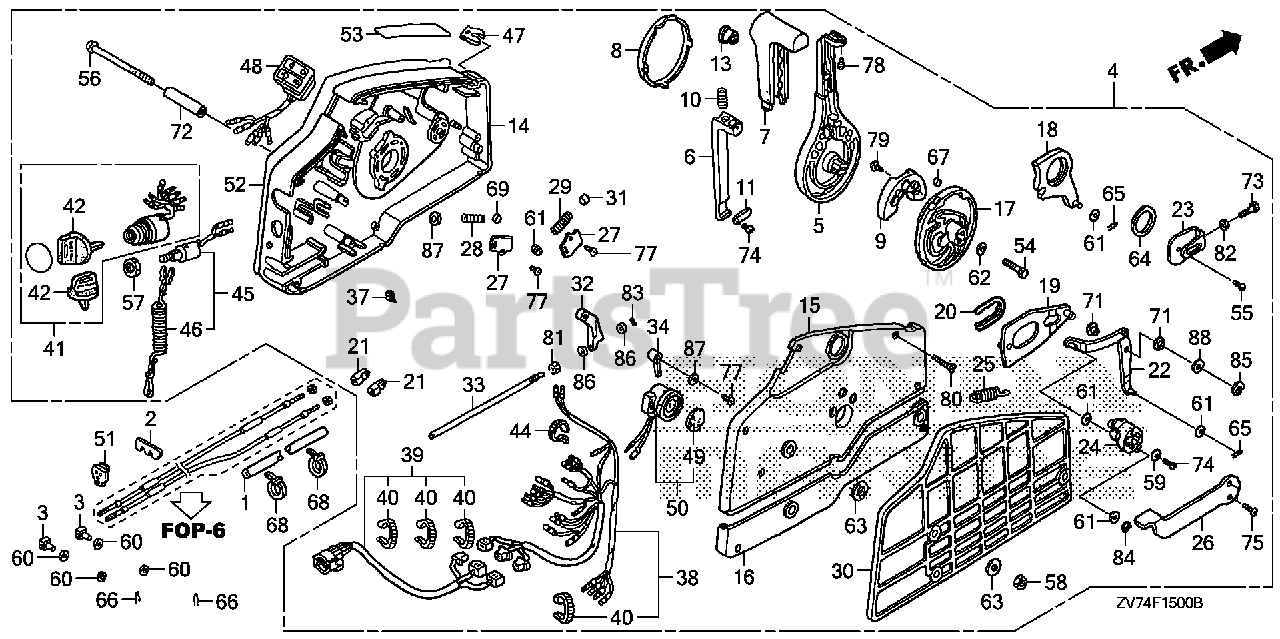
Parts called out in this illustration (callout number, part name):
1	TUBE, CORRUGATE (28MM)
2	PLATE, REMOTE CONTROL CABLE
3	PIVOT, SHIFT
4	S/R SW 2 LIGH MAN TL
4	BOX ASSY., REMOTE CONTROL (A/T)(HI-LEX)
5	HANDLE, REMOTE CONTROL
6	LEVER, HANDLE LOCK
7	GRIP, REMOTE CONTROL HANDLE
8	CAP, HANDLE
9	BLOCK, NEUTRAL LOCK
10	SPRING, REMOTE CONTROL HANDLE
11	PLATE, LEVER SETTING
13	COVER, GRIP
14	HOUSING, REMOTE CONTROL BOX (A)
15	HOUSING, REMOTE CONTROL BOX (B)
16	HOUSING, REMOTE CONTROL BOX (C)
17	WHEEL, CONTROL
18	ARM, SHIFT LINK
19	PLATE, SLIDING
20	COLLAR, SLIDING PLATE
21	PIVOT, SHIFT
22	ARM, LINK JOINT
23	BRACKET, LINK JOINT
24	WHEEL, ACCELERATOR
25	SPRING, ACCELERATOR WHEEL
26	LEVER, IDLE
27	PLATE, SPRING SETTING
28	SPRING, SHIFT CLICK
29	SPRING, CHOKE RETURN
30	SPACER, REMOTE CONTROL BOX
31	SPACER, CLICK SPRING
32	BLOCK, THROTTLE FRICTION
33	BOLT, FRICTION
34	SPACER, NEUTRAL SWITCH
37	SPACER, CABLE CLAMP
38	CABLE ASSY., REMOTE CONTROL (B)
39	CABLE ASSY., SWITCH PANEL
40	TIE, CABLE (2.4X92) (NATURAL)
41	SWITCH ASSY., COMBINATION
42	KEY ASSY., COMBINATION SWITCH (35100-ZV5-003 ONLY)
44	BAND (BLACK 3.5X140)
45	SWITCH ASSY., EMERGENCY STOP
46	WIRE, EMERGENCY
47	CLIP, EMERGENCY LOCK
48	LAMP ASSY., INDICATION (2-LED)
49	PLATE, TURN SIGNAL BUZZER
50	BUZZER, WARNING
51	GROMMET, CASE (LOWER) (A)
52	PLATE, REMOTE CONTROL (CAUTION PICT=SILVER)
52	PLATE, REMOTE CONTROL (COUTION COLOR=RED & YELLOW)
53	MARK, FAST IDLE
54	BOLT, FLANGE (8X35)
55	SCREW, PAN (6X10)
56	SCREW (6X95)
57	NUT, HEX. (16MM)
58	NUT, HEX. (6MM)
59	WASHER, PLAIN (5MM)
60	WASHER, PLAIN (6MM)
61	WASHER, PLAIN (6MM)
63	WASHER (6MM)
64	WASHER (28MM)
65	PIN, LOCK (6MM)
66	PIN, SPECIAL LOCK (6MM)
67	PIN (6X6)
68	BAND, SELF-LOCK
69	ROLLER, CLICK
71	COLLAR, LINK JOINT
72	COLLAR, DISTANCE (6X10X43.5)
73	BOLT, HEX. (5X16)
74	SCREW, PAN (5X10)
75	SCREW, FLAT (5X12)
77	SCREW, TAPPING (5X10)
78	SCREW, TAPPING (5X12)
79	SCREW, TAPPING (6X16)
80	SCREW, TAPPING (5X25)
81	NUT, HEX. (6MM)
82	NUT, HEX. (5MM)
83	E-RING (3MM)
84	E-RING (4MM)
85	E-RING (7MM)
86	WASHER, PLAIN (4MM)
87	WASHER, PLAIN (5MM)
88	WASHER, PLAIN (8MM)
